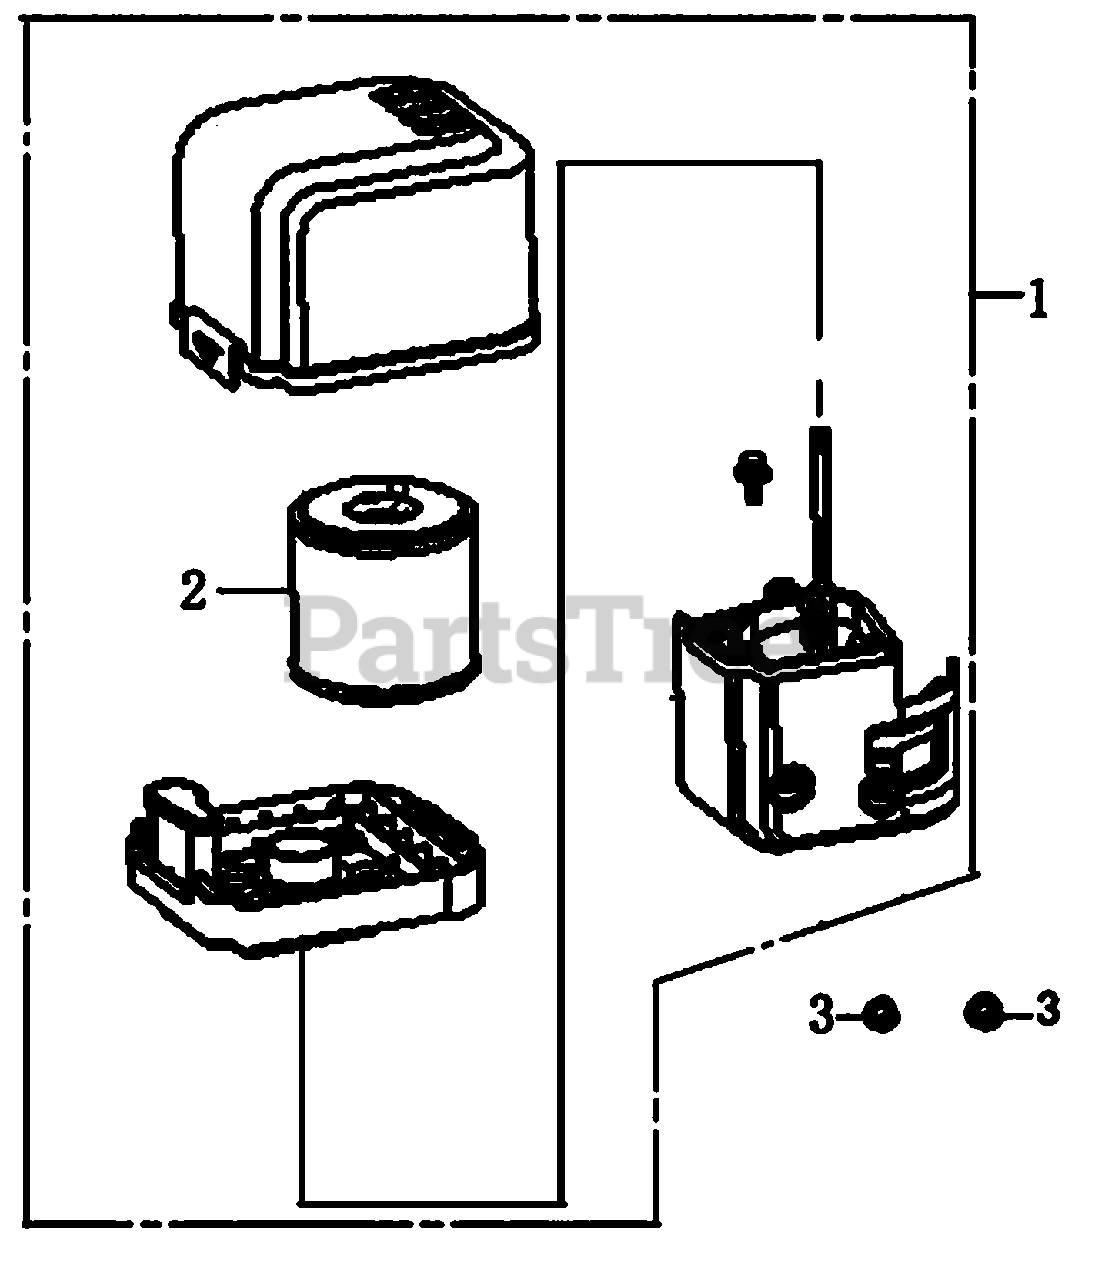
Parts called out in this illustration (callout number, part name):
1	AIR CLEANER ASSY
2	ELEMENT ASSY, AIR CLEANER
3	NUT, FLANGE M6
